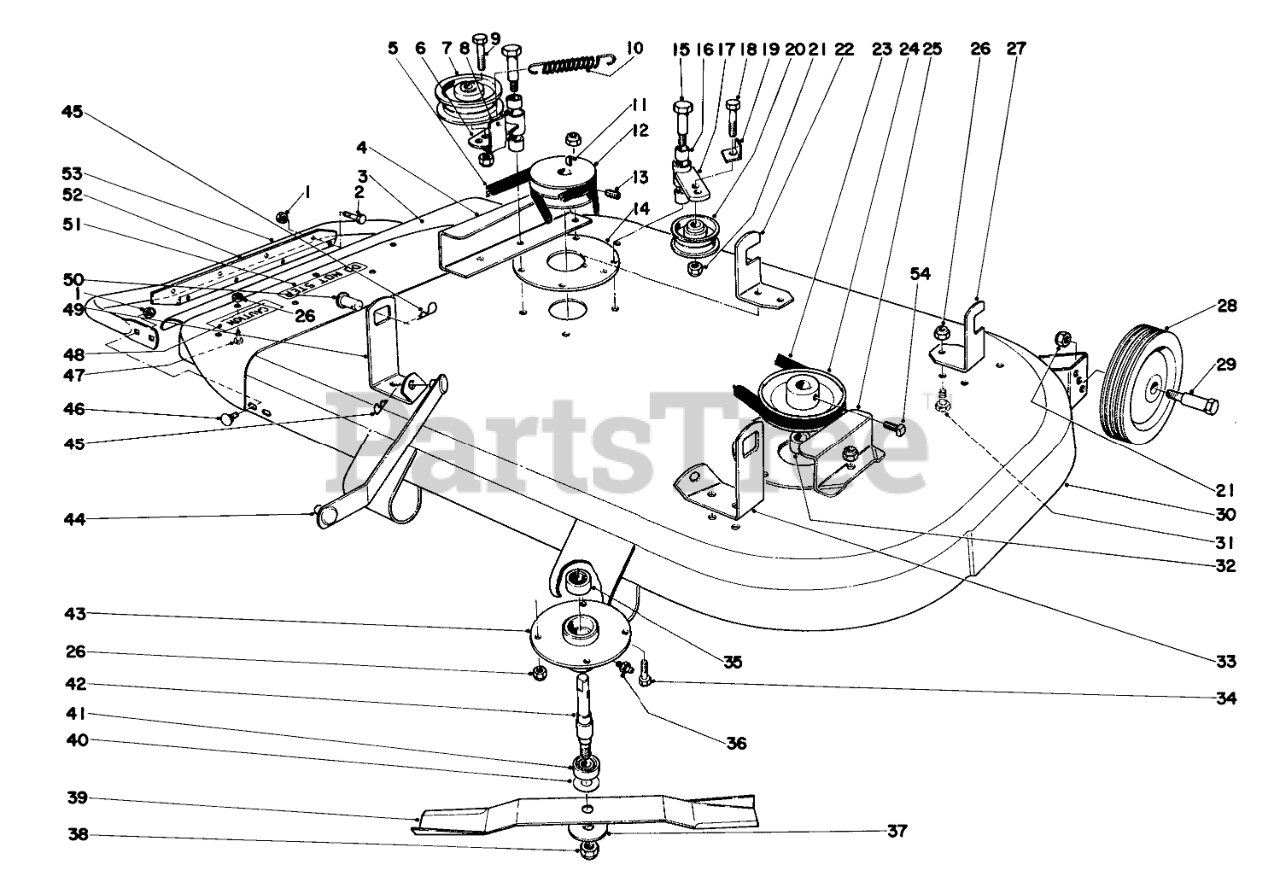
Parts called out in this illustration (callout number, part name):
2	SCREW-HH
3	Deflector Plate
4	Guard Mower
5	V-BELT
6	Idler Plate (Incl. Ref. #16)
7	Idler Pulley
8	Retainer Belt
9	SCREW-HH
10	Spring Tension
11	KEY-WOODRUFF
12	BLD SPDLE PULLEY (MACH)
13	SCREW-SET, HSH
14	Washer
15	SHOULDER BOLT
16	BUSHING
17	Idler Plate
18	SCREW-HH
20	Idler Pulley
21	NUT-LOCK, CONE
22	Bracket
24	Pulley
25	Belt Guard
26	NUT-LOCK, CONE
27	Bracket Mower
28	Wheel
29	Axle Bolt
30	Housing
31	SCREW-HH
32	Spacer
33	Bracket-Mower
34	SCREW-HH
35	Bearing
36	FITTING-GREASE
37	WASHER
38	NUT-LOCK, CONE
39	Blade
40	WASHER
41	.6693 RP BALL BEARING
42	Blade Spindle
43	MOWER SPINDLE HOUSING
44	Tow Bar
45	PIN-COTTER
46	SCREW-CARR
47	5/16-18X5/8 TRS HD MS
48	Decal
49	Bracket-Mower
51	Decal
52	Bar-Deflector
53	Mower Guard
54	5/16-18 X 1/2 SQ HD
